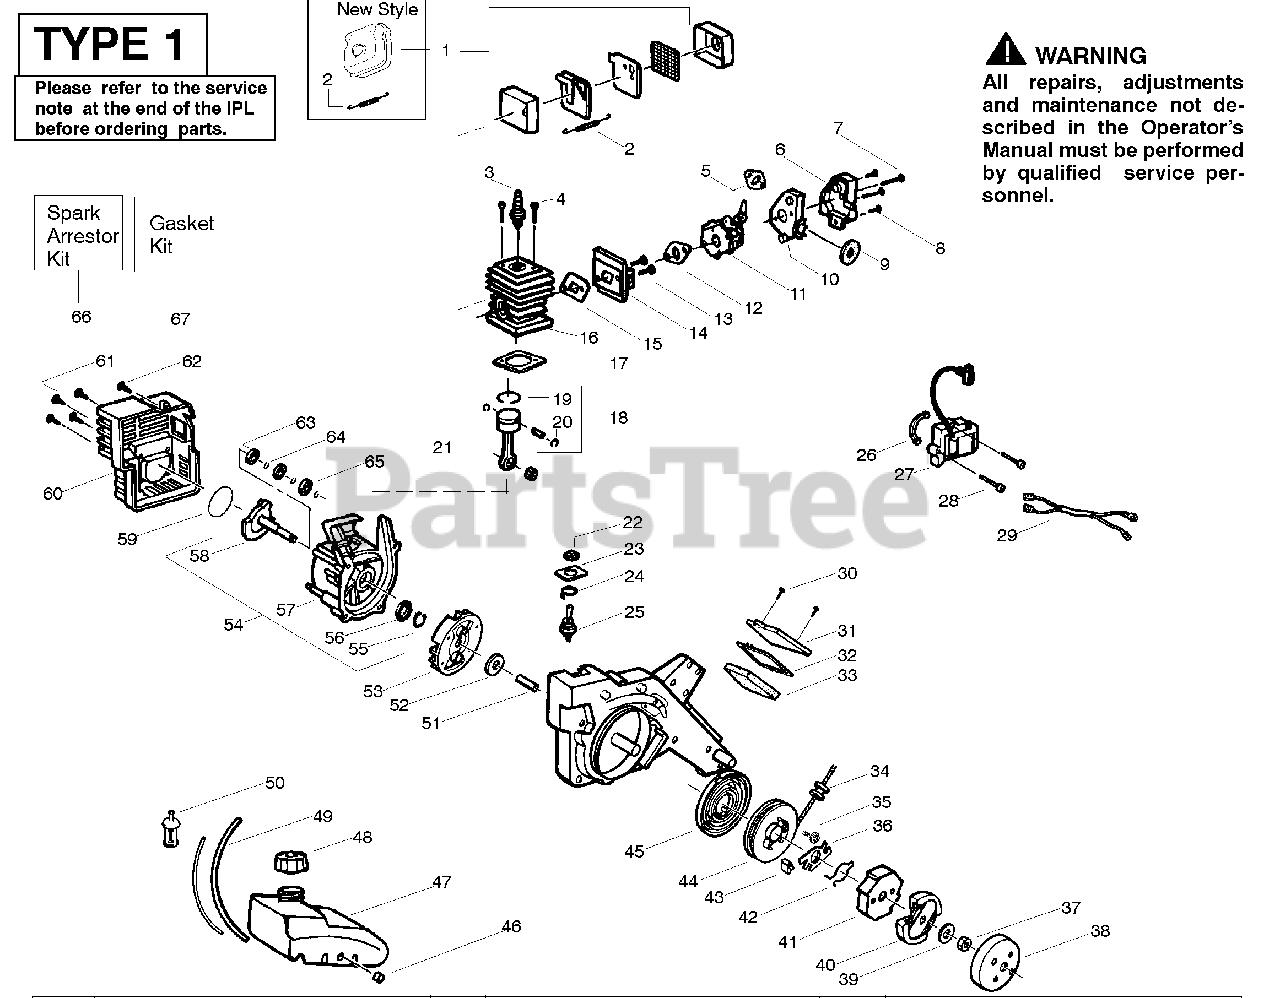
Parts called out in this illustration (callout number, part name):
1	Kit-Muffler (Old Style)
1	Kit-Muffler (New Style)
2	Spring-Muffle (Old Style)
2	Spring-Muffle (New Style)
3	Plug-Spark (RCJ-8Y)
5	Gasket-Carb/Bracket(kit)
6	Cover-Air Box
9	Seal-Foam (kit)
10	Base-Air Box
11	Kit-Carb. (WT308)
12	Gasket-Carb.(kit)
14	Adapter-Carb.
15	Gasket-Cyl./Carb. (kit)
16	Kit-Cylinder
17	Gasket-Cyl. (kit)
18	Kit-Piston
19	Retainer-Pin
20	Ring-Piston
21	Kit-Conn. Rod Assy.
22	Boot-Switch w/nut
23	Plate-Switch Indicator
24	Terminal-Grounding
25	Assy-Gound Switch
26	Spacer-Module
27	Module-Ignition
29	Assy-Switch Wire
31	Cover-Air Filter
32	Gasket-Cover (kit)
33	Foam-Air Filter
36	Cam-Starter
38	Drum-Clutch
39	Washer-Flywheel
40	Assy-Clutch
41	Cup-Starter
42	Wire-Starter Dog
43	Dog-Starter
44	Kit-Starter Pulley
45	Spring-Starter
46	Isolator-Crankcase
47	Assy-Fuel Tank
48	Assy-Fuel Cap
49	Kit-Fuel Line
50	Assy-Fuel Pick-up
51	Spacer-Flywheel
52	Washer-Flat
53	Assy-Flywheel
54	Assy-C/shaft & C/case
55	Retainer-C'shaft
56	Seal-Crankcase
57	Assy-C'case
58	Assy-Crankshaft
59	O-ring-c'case/shrd (kit)
61	Screw
63	Bearing-Inner
64	Retainer-C'case
65	Bearing-Outer
66	Kit-Spark Arrestor (Old Style)
66	Kit-Spark Arrestor (New Style)
67	Kit Gasket
